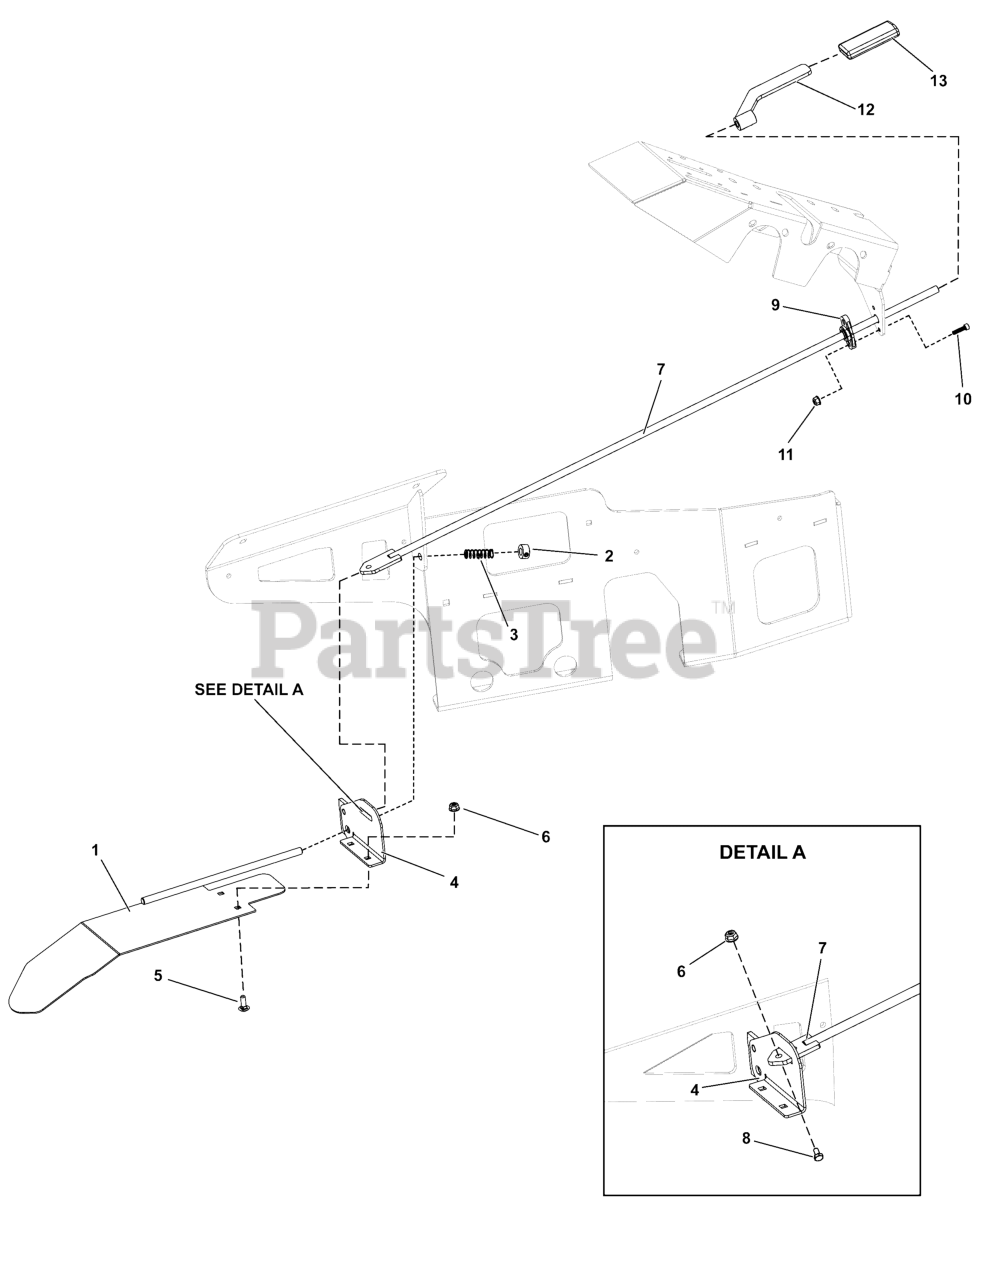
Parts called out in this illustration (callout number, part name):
1	WELD, DIVERTER SHIELD VOYAGER
2	COLLAR, SHAFT .375ID X .750OD X .375WD
3	SPRING, COMPRESSION .480" OD X 1.500 LONG SS
4	BRACKET, ACTUATE DEFLECTOR
5	BLT-RDHDSQNK .250"-20 X .750" SS188
6	NUT-HEX-NYLK, FLG .250"-20 SS188
7	WELD, TRIM SHIELD DRIVE
8	SCR-CAP, HEX .250"-20 X .500" SS188
9	BEARING, FLANGE IGUS EFOI-6
10	SCR-CAP, SH #10-24 X .750" SS188
11	NUT-HEX-NYLK, FLG .#10-24 SS188
12	WELD, LEVER TRIM SHIELD
13	GRIP, .188" X 1.00" ID X .150" THK CLSD CELL FOAM
